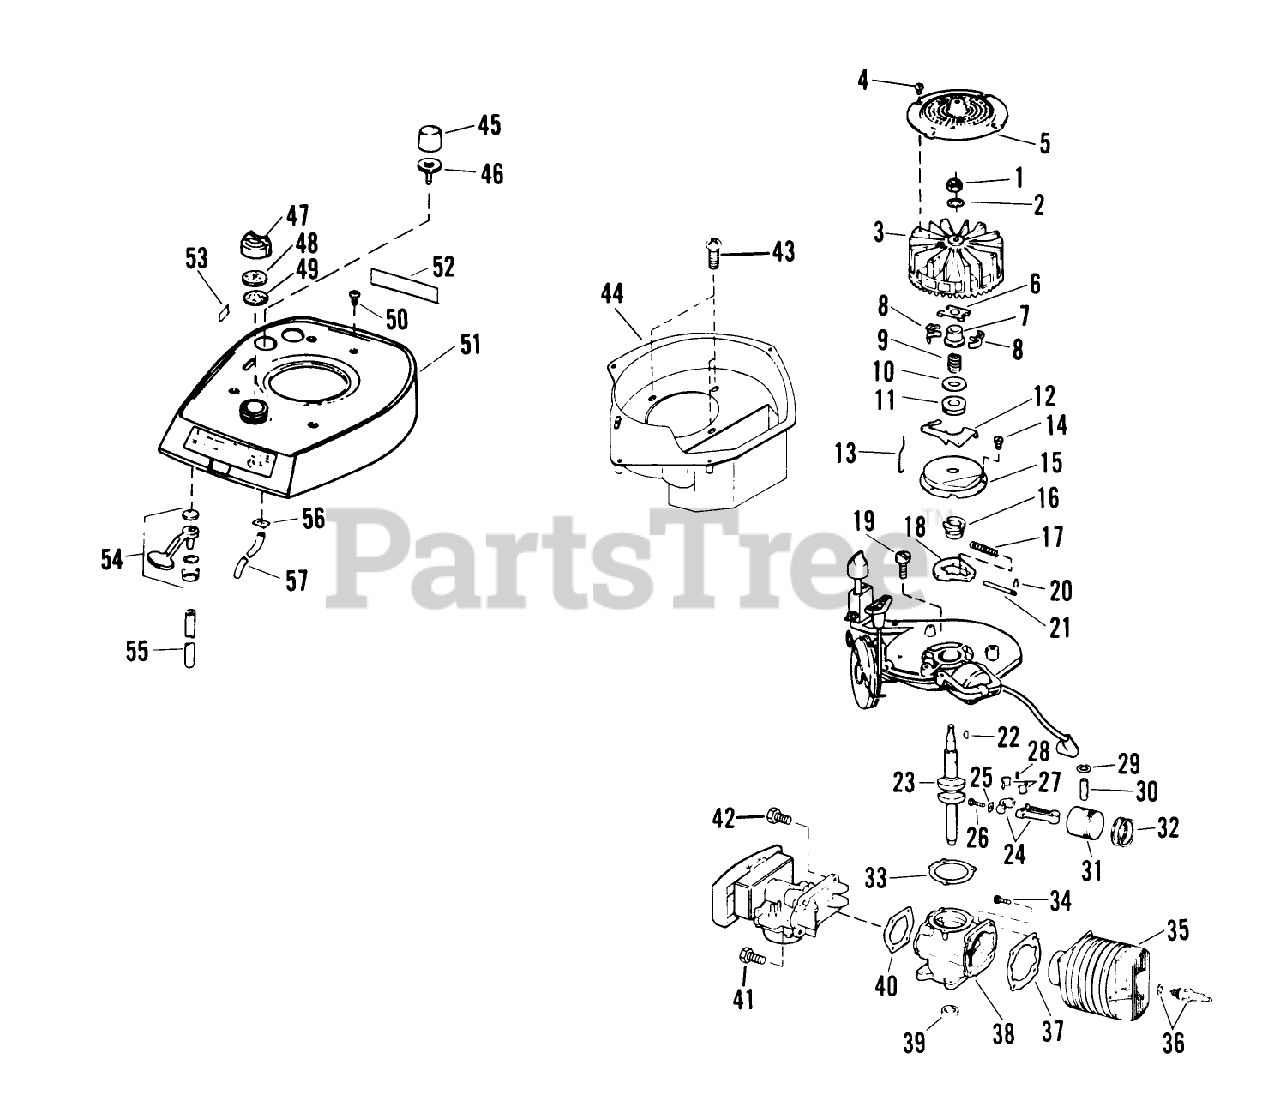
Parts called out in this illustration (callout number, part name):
4	SCREW F
5	FLYWHEEL SCREEN
7	COLLAR S
11	THRUST COLLAR S
12	LEVER-GOVERNOR S
14	SCREW S
15	DUST COVER S
16	SPARK ADV. S
17	SPARK ADV. SPRING S
18	FLYWEIGHT S
20	SPARK ADJ. SPRING
21	PIN,SPARK ADV. S
27	LINER ASM
29	RING-RETAINING
33	GASKET S
36	Spark Plug Gasket
37	GASKET S
40	GASKET S
41	SCREW S
42	SCREW S
48	BAFFLE - FOAM SM
49	GASKET S
50	SCREW S
56	LOCKNUT S
57	Tube-Primer
